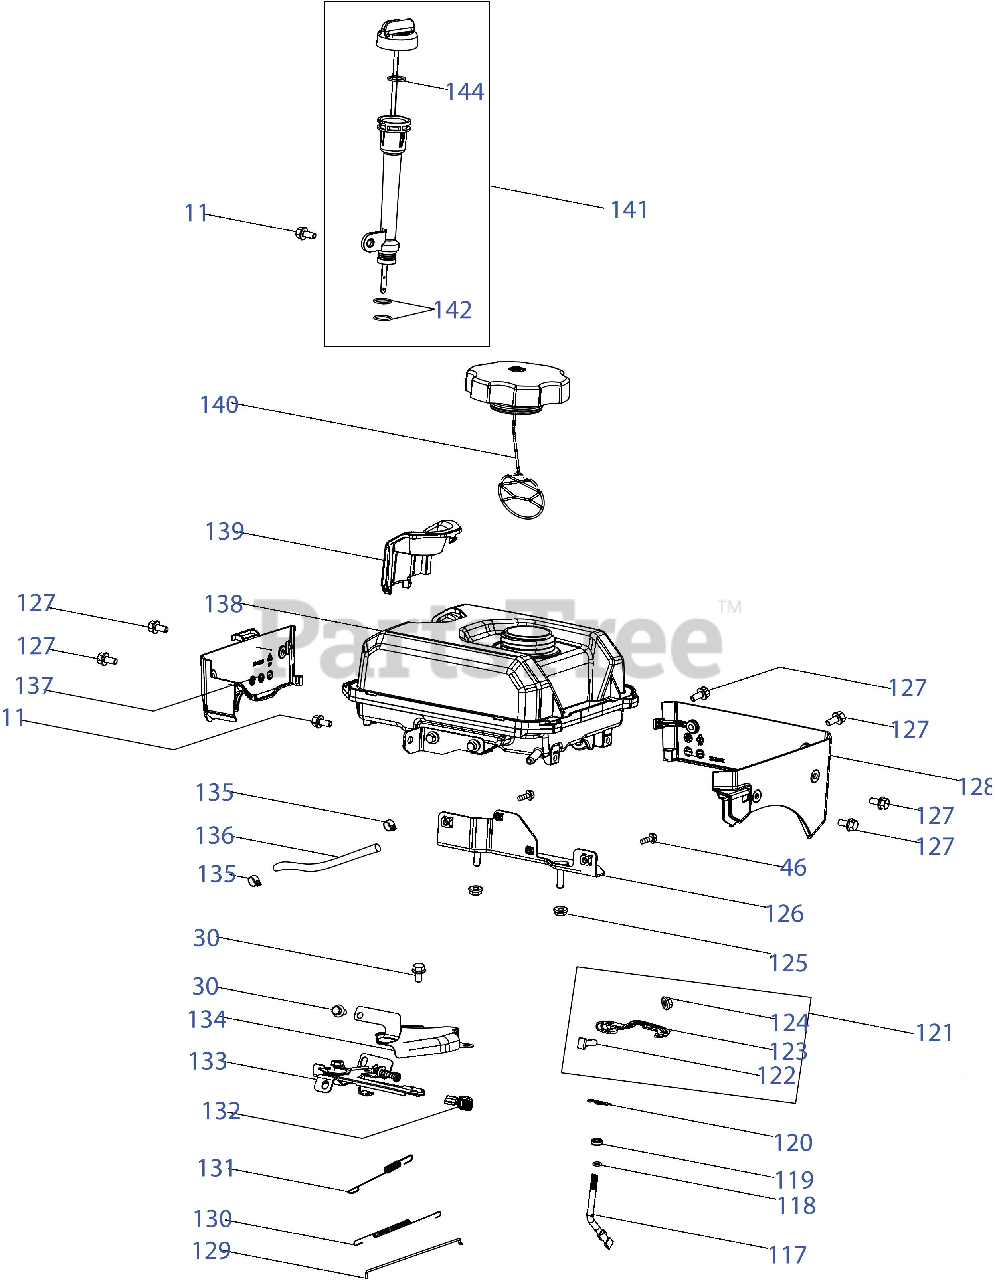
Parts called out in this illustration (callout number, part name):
11	Bolt, M6?12
30	Bolt, M6?12
46	Bolt, M6?18
117	Governor Gear Shaft
118	O-Ring, 5.2?1.9
119	Oil Seal, 6?11?4
120	Cotter Pin
121	Governor Lever
122	Bolt, M6?21
123	Governor Lever
124	Nut, M6
125	Nut, M6
126	Fuel Tank Bracket
127	Bolt, M5?14
128	Decorative Sheet, Left
129	Throttle Linkage
130	Idle Spring
131	Governor Spring
132	Throttle Lever Knob
133	Governor Gear Bracket Assembly
134	Governor Shield
135	Clamp
136	Fuel Hose, 6.3?12.5?162
137	Decorative Sheet, Right
138	Fuel Tank
139	Decorative Cover
140	Fuel Cap
141	Dipstick
142	O-Ring, 15.2?1.5
144	O-Ring, 21?2.77
